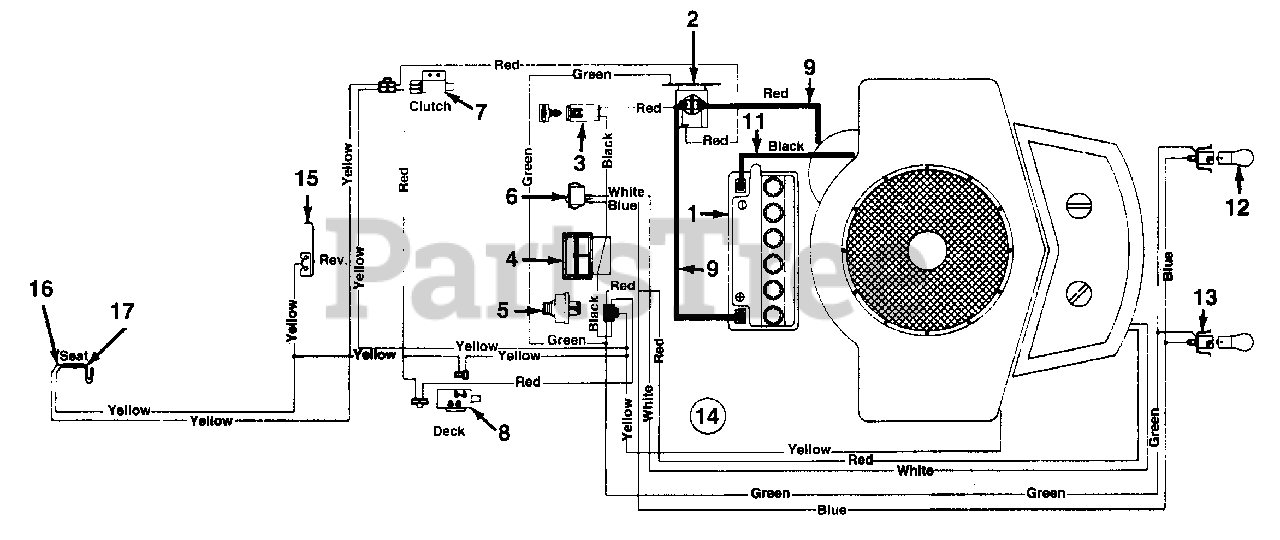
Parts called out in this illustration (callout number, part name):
1	Battery
2	Solenoid
3	Fuse 7.5 Amp
4	Ammeter
5	Ignition Switch
6	Light Switch
7	Safety Switch (Clutch)
8	Safety Switch (PTO)
9	Electric Wire 14" Lg.
11	Ground Wire 7.5" Lg.
12	Lamp
13	Socket
14	Wire Harness
15	Spring Switch (Reverse)
16	Spring Switch (Seat)
17	Spring Switch (Seat)
